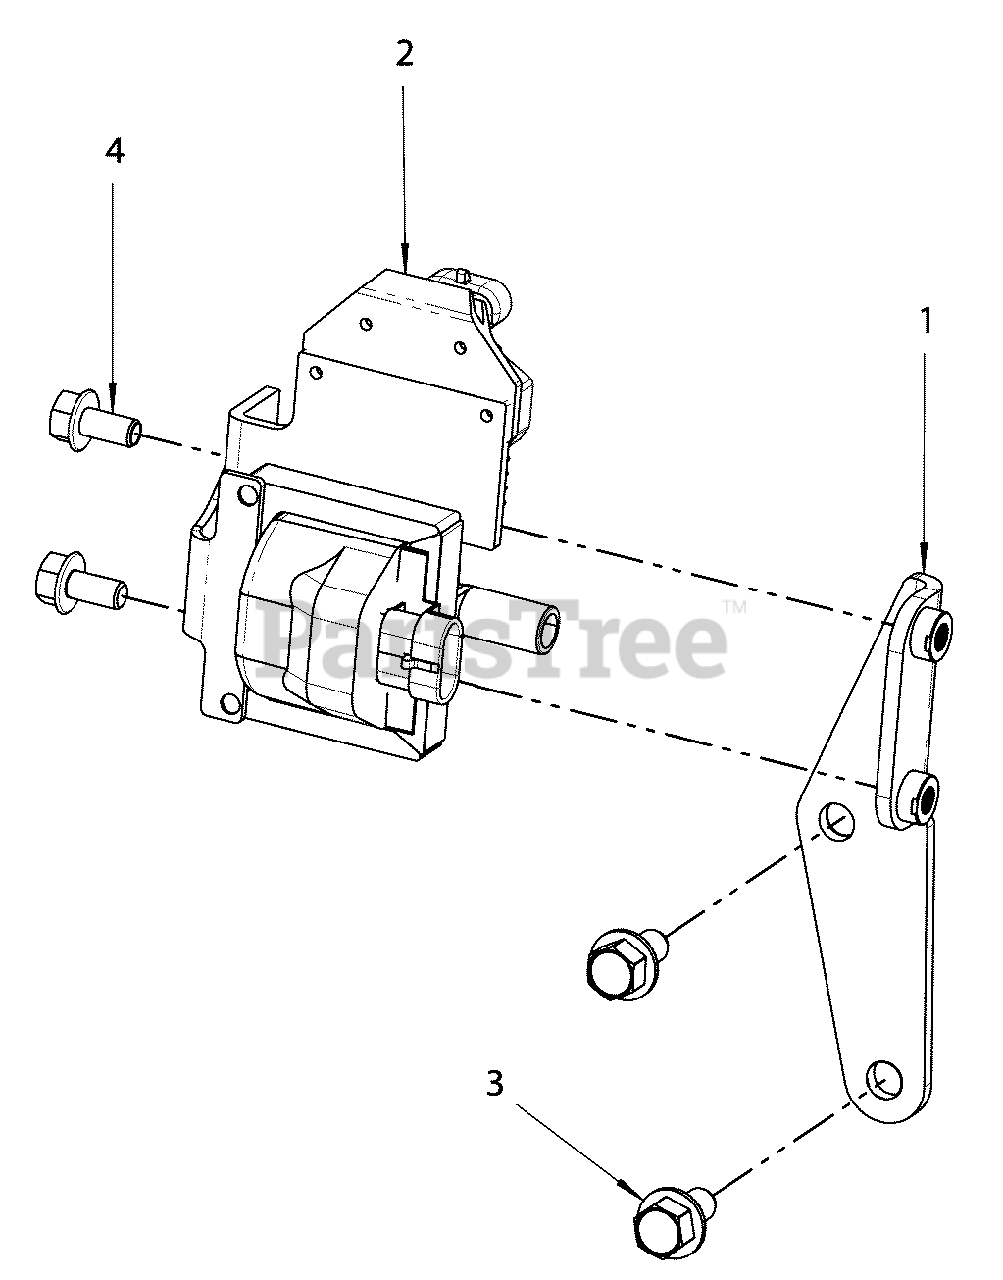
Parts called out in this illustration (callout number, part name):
1	BRACKET
2	COIL, IGNITION
3	BOLT
4	SCREW
